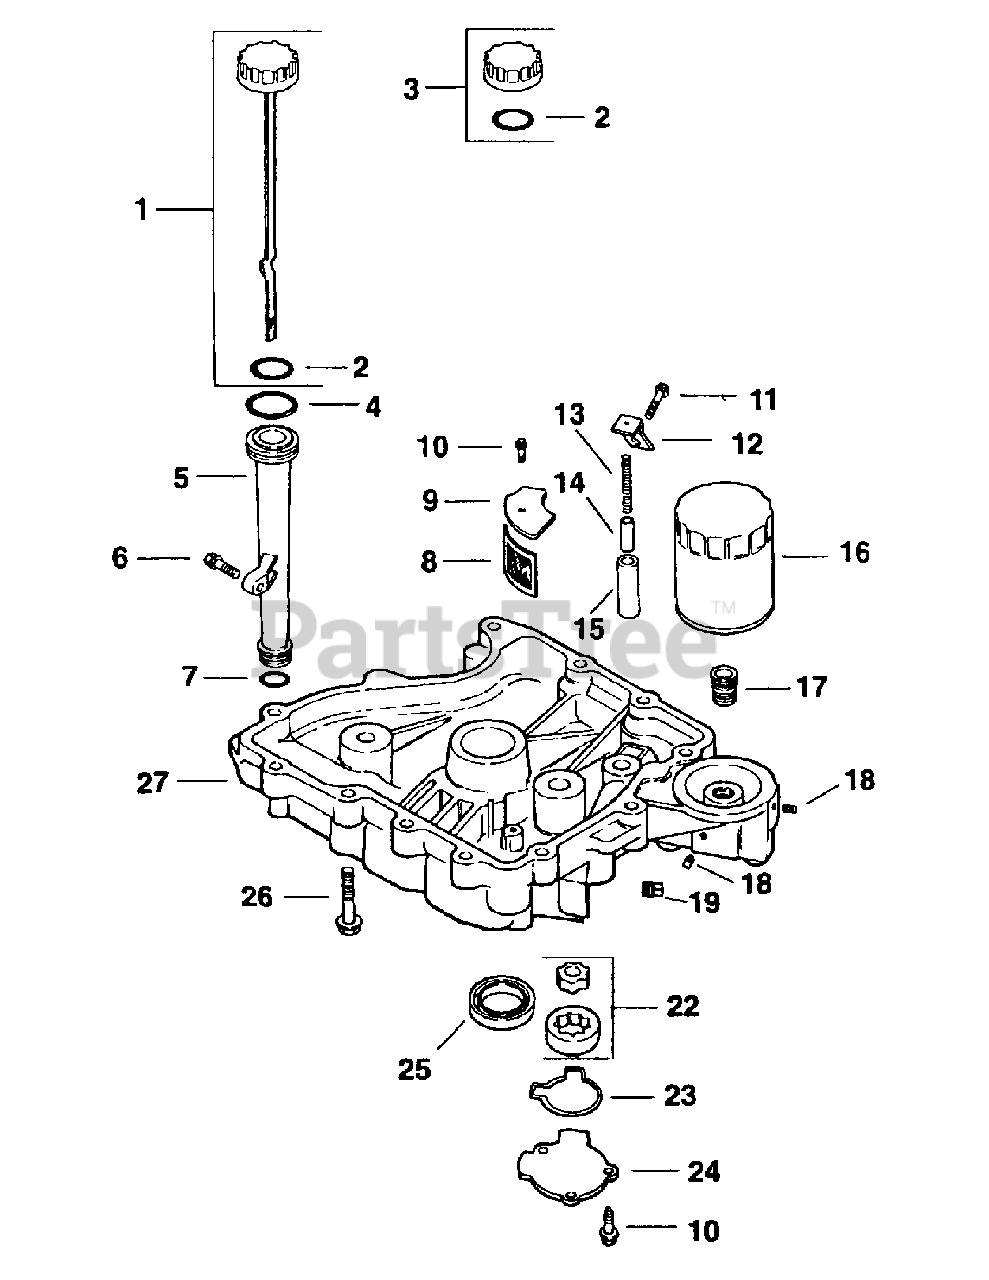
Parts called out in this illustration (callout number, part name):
1	Dipstick Assembly
2	O-Ring, Dipstick
3	Oil Fill Cap Kit
4	O-Ring, Oil Fill Tube (upper)
5	Tube, Oil Fill
6	Screw, Hex Flange
7	O-Ring, Oil Fill Tube (lower)
8	Screen, Oil Pick-Up
9	Cover, Oil Pick-Up Screen
10	Screw, Hex Flange
11	Screw, Hex Flange
12	Bracket, Oil Pump Relief
13	Spring, Oil Pump Relief Valve
14	Piston, Oil Pump Relief Valve
15	Body, Oil Pump Relief Valve
16	Filter, Oil
17	Adapter, Oil Filter
18	Plug, Sq. hd. Solid 1/8" N.P.T.F.
19	Plug, Sq. hd. Solid 3/8" N.P.T.F.
22	Pump, Oil
23	O-Ring, Oil Pump Cover
24	Cover, Oil Pump
25	Seal, Oil (PTO End)
26	Screw, Hex Flange
